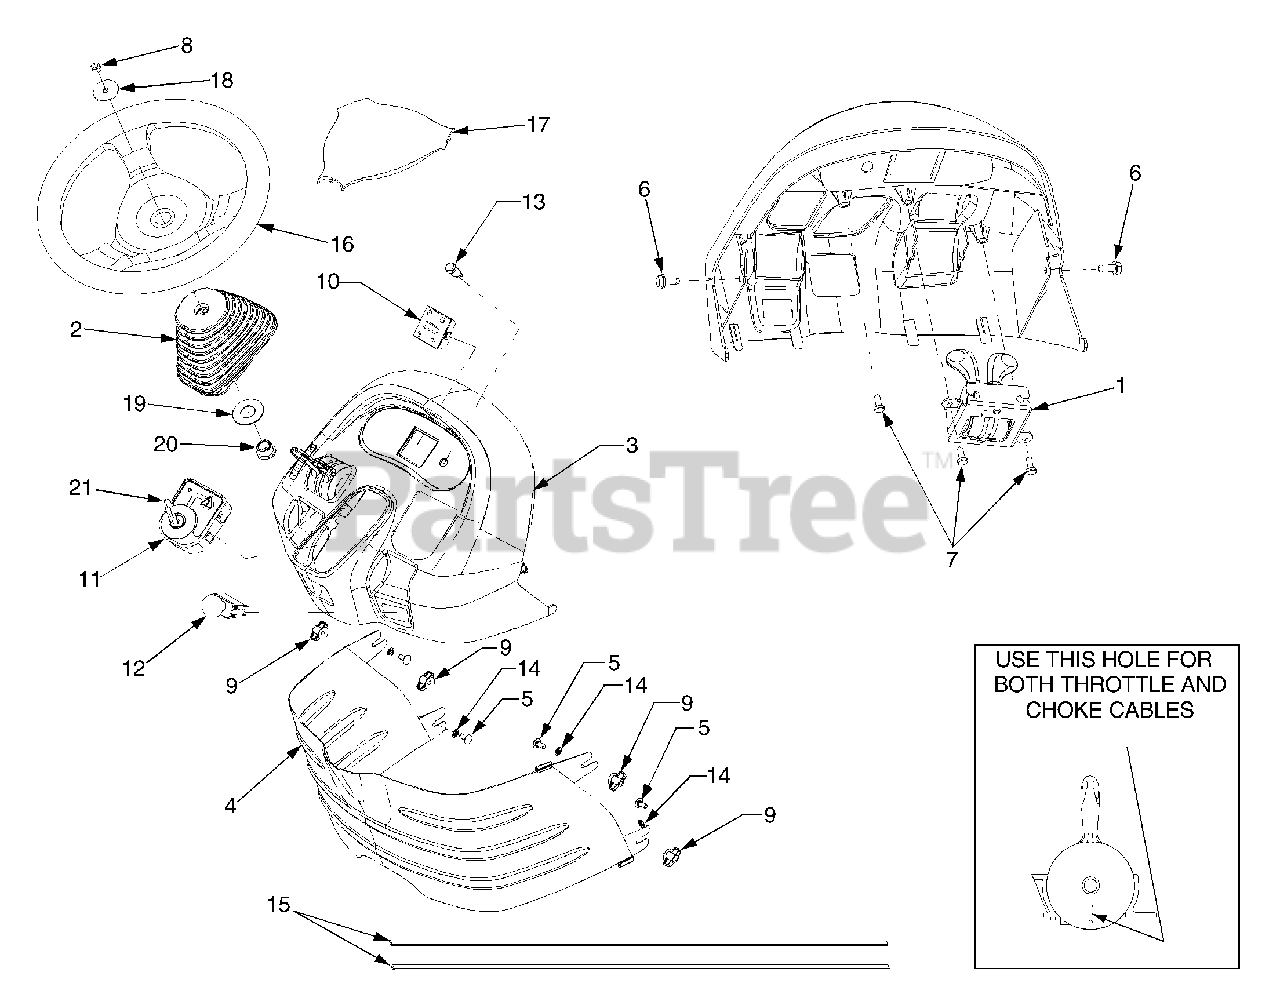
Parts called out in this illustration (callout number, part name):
1	Control Ass'y, Throttle/Choke
2	Boot, Tilt Steer
3	Dash Panel
3	Graphic, Monitor Light Cover
6	Screw, Hex Wash. Hd. Tapp 5/16-18 x .75
7	Screw, Hex Cap 1/4-20 x .50 GR5
8	Nut, Hex Lock, 5/16-24
9	Wing Nut, 1/4-20 w/Bell Washer
10	Meter, Indicator / Hour
11	Switch, Key/Module
12	Switch, PTO
13	Lamp, Fuel
14	Nut, Push
15	Seal, Screen
16	Steering Wheel
17	Cover, Steering Wheel
18	Washer, Flat, .34 x 1.5 x .10
19	Washer, Flat, .885 x 1.85 x .06
20	Bearing, Flange, .63ID x .62 Lg
21	Key, Ignition
